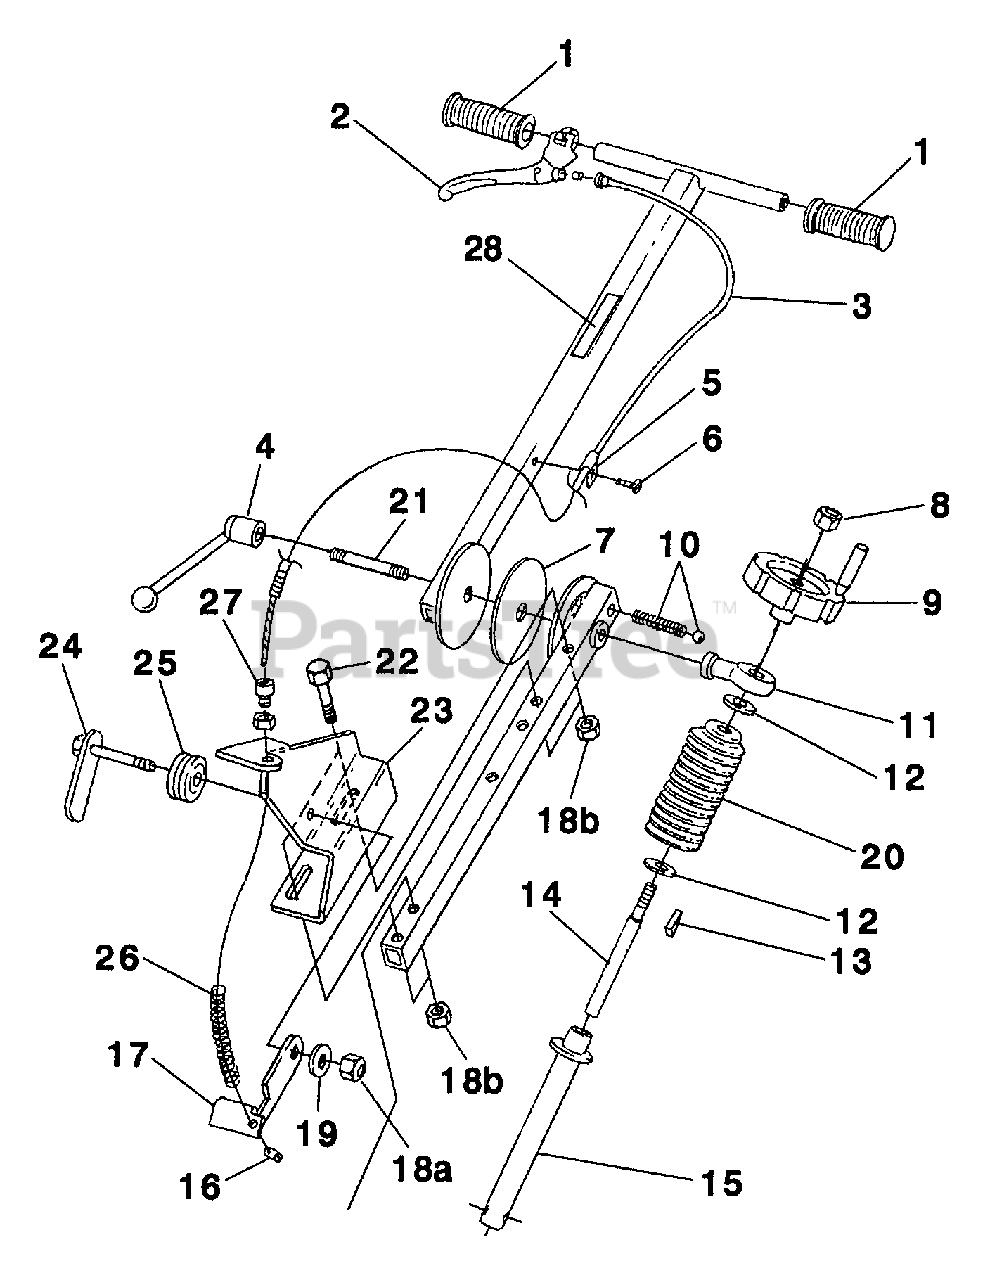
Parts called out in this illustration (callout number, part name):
1	Handle Grip
2	Throttle Lever
3	Throttle Cable
4	Locking Handle
5	Cable Casing Clamp
6	Screw, Slotted 10-32 x .5
7	Neoprene Disk
8	Nut 3/16-18
9	Handwheel
10	Detent & Spring
12	Flat Washer (.438)
13	Woodruff Key
14	Depth Screw
15	Depth Adjusting Tube
16	Locking Barrel & Screw
17	Trigger Lever
18A	Nut 5/16
18B	Nut 5/16
19	Flat Washer
21	Handle Stud
22	Bolt 5/16-18 x 2.25
23	Rear Handle Bracket
24	Clamp & Bolt Assembly
26	Throttle Spring
27	Barrel Adjuster
28	Warning Decal
